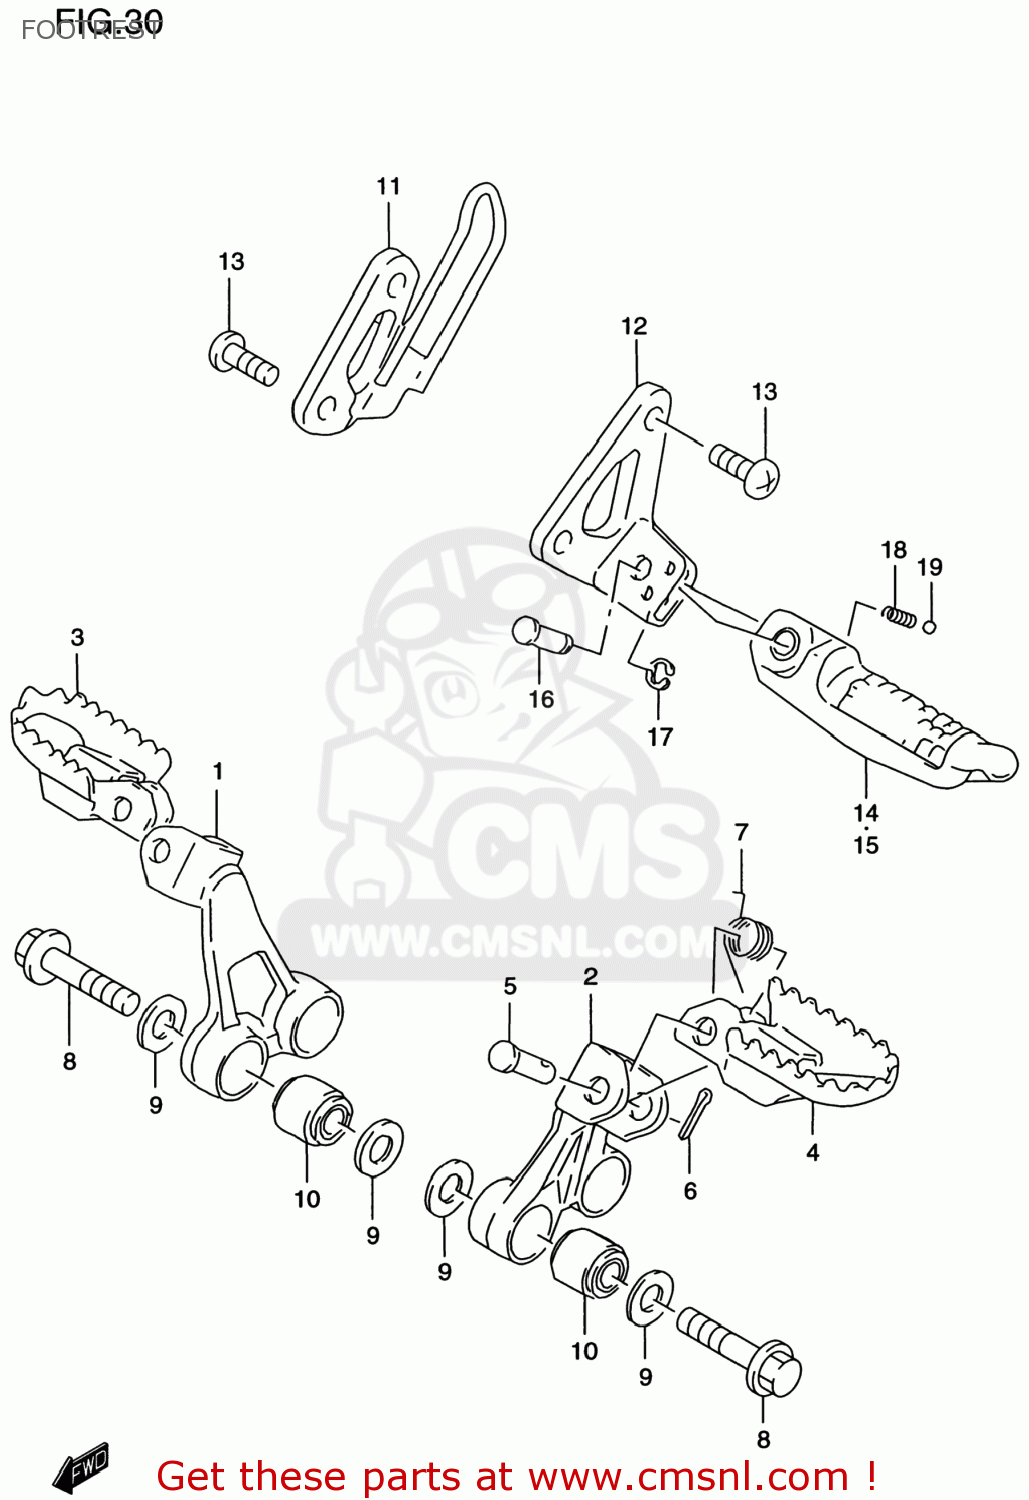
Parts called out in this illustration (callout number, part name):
1	BRACKET,FR FOOTREST,R
2	BRACKET,FR FOOTREST,L
3	FOOTREST,FRONT,RIGHT
4	FOOTREST,FRONT,LEFT
5	PIN
6	PIN 20X20
7	SPRING
8	BOLT(10X50)
9	WASHER
10	BUSH(10.2X25X19)
11	BRACKET,PILLION FOOT,R(BLACK)
12	BRACKET,PILLION FOOT,L(BLACK)
13	BOLT 8X20
14	BAR,PILLION FOOTREST,R
15	BAR,PILLION FOOTREST,L
16	PIN
17	E.RING
18	SPRING
19	BALL
